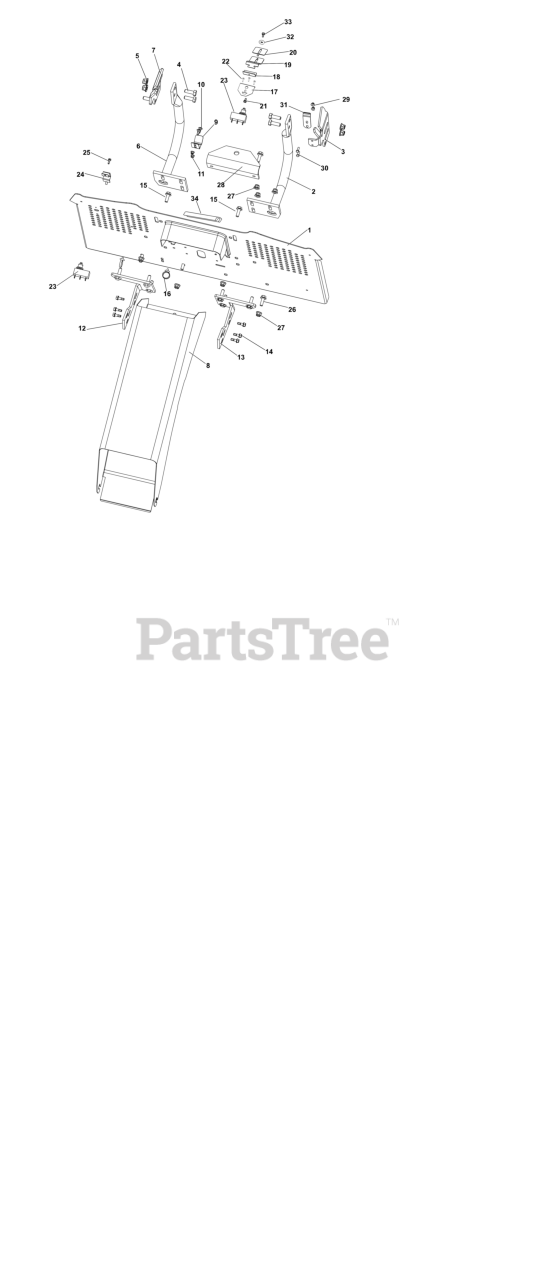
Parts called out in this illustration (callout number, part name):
1	PLATE, Back
8	CHUTE, Discharge
23	MICROSWITCH
24	SWITCH, Cover
